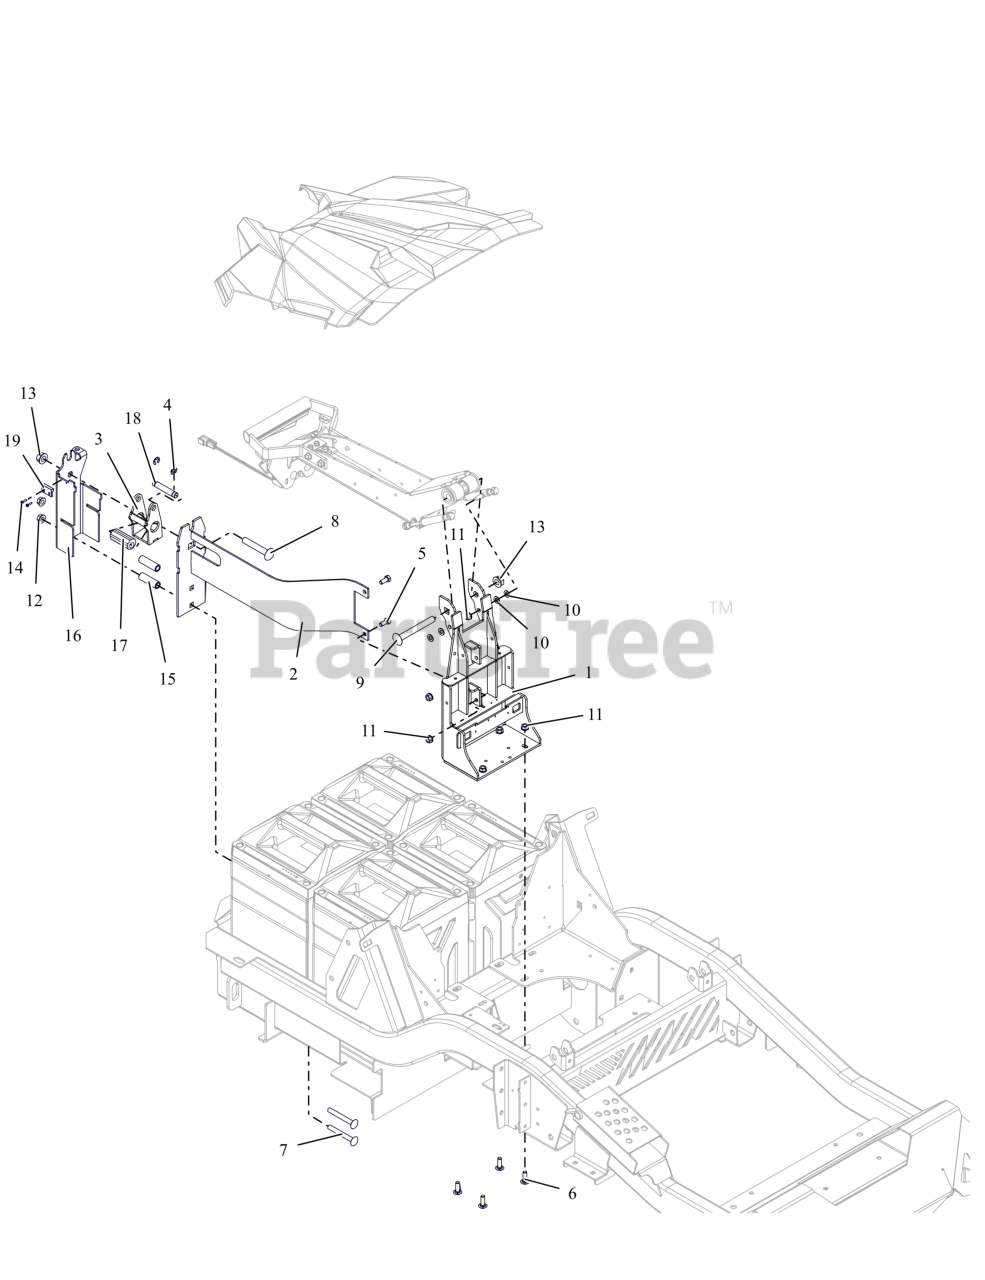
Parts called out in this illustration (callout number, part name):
1	WLDMT, BATTERY HOLDDOWN PIVOT (ORANGE)
2	WLDMT, ECCENTRIC MTG (ORANGE)
3	WLDMT, ECCENTRIC
4	RG-RTNG-EXT .438X.035
5	BLT,HEX .31-18X.75 G5 ZCC
6	BLT,RHSSN .31-18X1.00 G5 ZCC
7	BTL,RHSSN .375-16 X 3 G5 ZCC
8	BTL,RHSSN .500-13 X 3 G5 ZCC
9	BTL,RHSSN .500-13 X 4.25 G5 ZCC
10	WSHR,FLT .323X.625X.062 ZCC
11	NUT,LK-CTR-FLG .31-18 GF ZCC
12	NUT-LK-CTR-FLG .375-16 GF ZCC
13	NUT-LK-CTR-FLG .500-13 GG ZCC
14	SCR-TAP #4-40x.50 HWH ZCC
15	SPCR, LATCH BRKT (BLACK)
16	BRKT, ECCENTRIC MTG (ORANGE)
17	ECCENTRIC, HOOD LATCH
18	ROD, LATCHING
19	SWITCH, MAGNET (NO WIRE)
